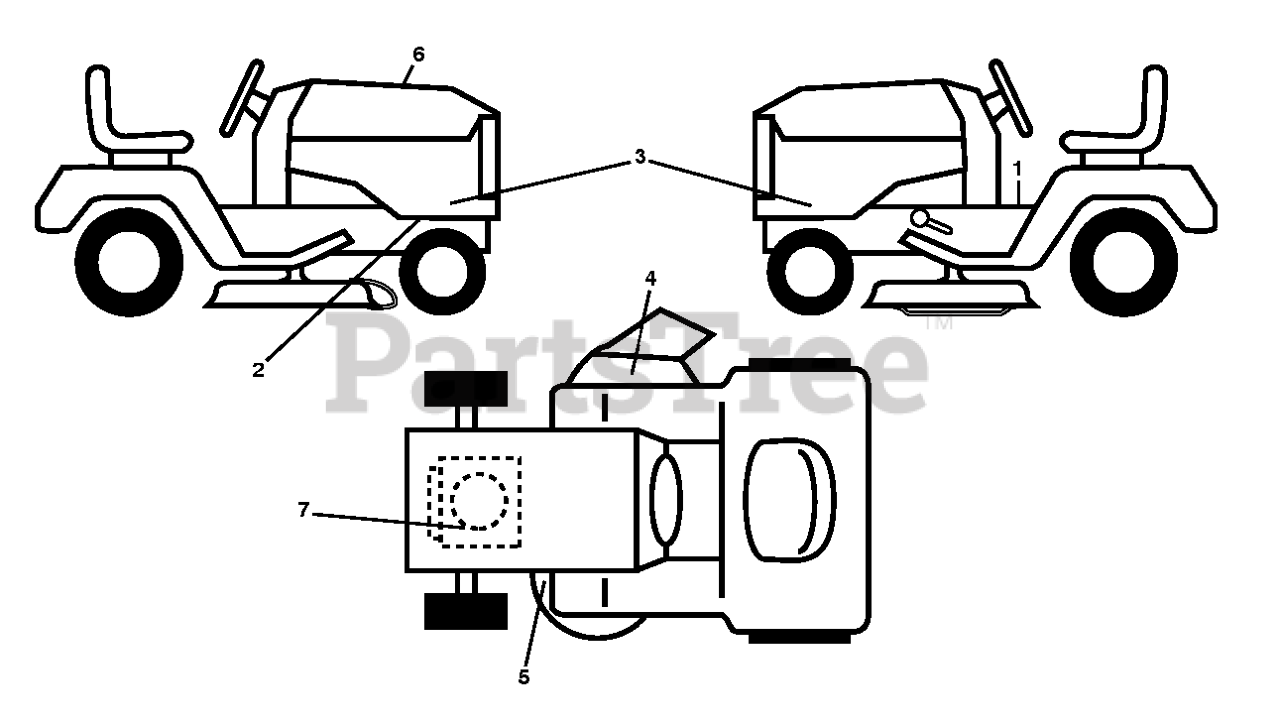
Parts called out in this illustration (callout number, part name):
1	DECAL.WARNING.2007.ENG/FR
2	DECAL.DRAWBAR.LOCKINGDIFFERENT
4	DECAL, DECK DEFLECTOR, WARNING
5	DECAL.V-BELT.SCH.42/46"MEC/ELE
7	DECAL DECAL.ENG.BS.ENDUR.22HP.
